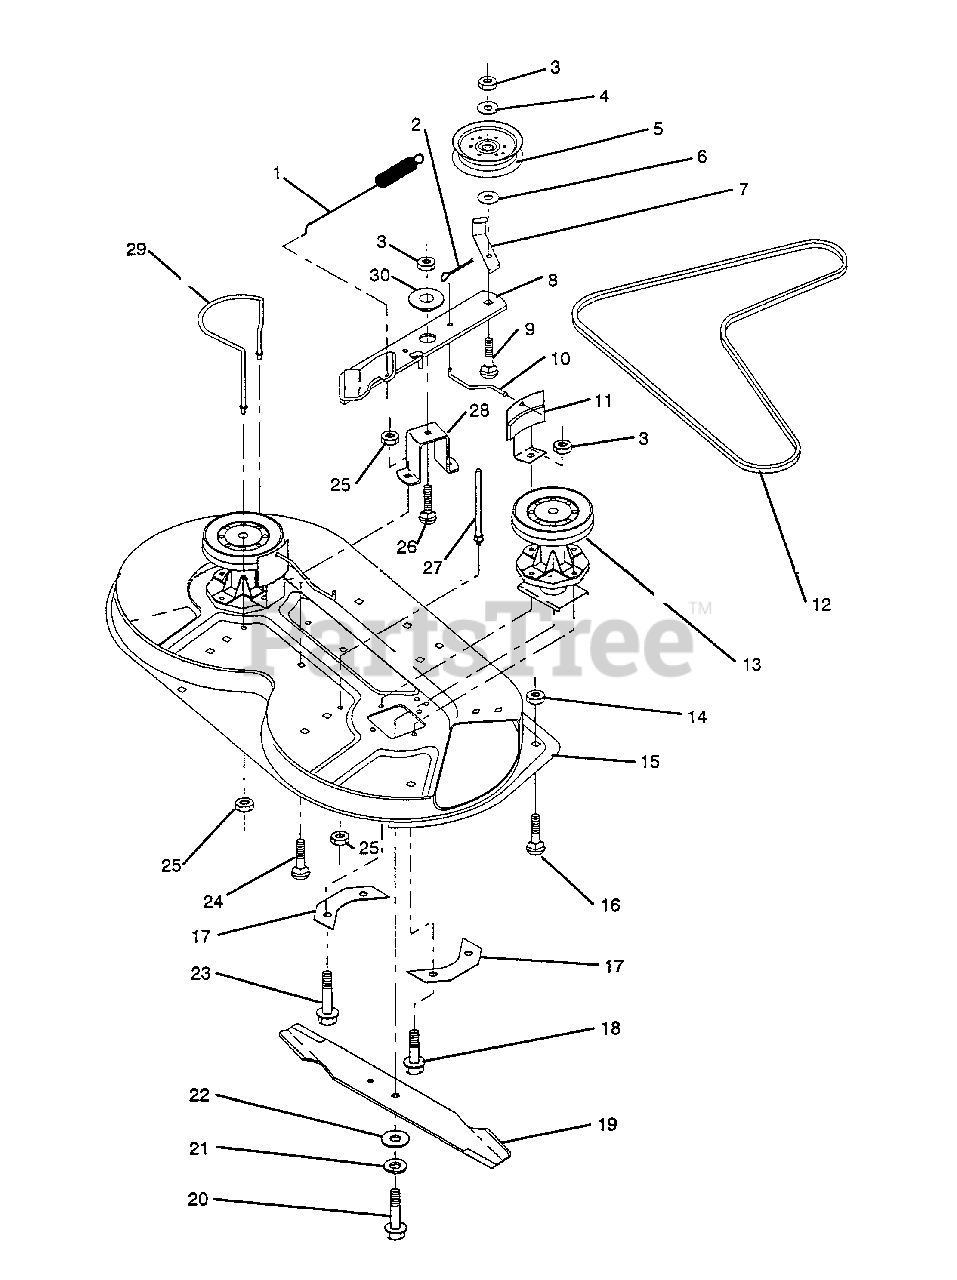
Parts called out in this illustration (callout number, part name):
1	Spring, Mower Clutch
2	Pin, Cotter 3/32 x 3/4
3	Nut, Crownlock 3/8-16 UNC
4	Washer 13/32 x 7/8 x 12 Ga.
5	Idler, Flat
6	Washer 13/32 x 1-3/8 x 13 Ga.
7	Guide, Belt
8	Assembly, Mower Idler Arm
9	Bolt, Carriage 3/8-16 x 2-1/4
10	Rod, Brake
11	Assembly, Brake
13	Assembly, Mandrel
14	Nut, Crownlock 1/4-20
15	Housing, Mower 36"
16	Bolt, Carriage 1/4-20 x 1/2
17	Support, Plate Jackshaft
18	Screw Hex Thdrol. 3/8-16 x 7/8
19	Blade, 60 Degree High Lift
20	Bolt, Fin. Hex 3/8-24 UNF x 1-1/2 Gr. 5
21	Washer, Lock Hvy.3/8
22	Washer 13/32 x 1-1/4 x 12 Ga.
23	Screw Hex Thdrol. 3/8-16 x 1-1/4
24	Bolt, Carriage 5/16-18 UNC x 5/8
25	Nut,Crownlock 5/16-18
26	Bolt, Carriage 3/8-16 UNC x 1 Gr. 5
27	Guide, R.H. Rear Belt
28	Support, Idler Arm
29	Guide, L.H. Belt
30	Spacer, Retainer
